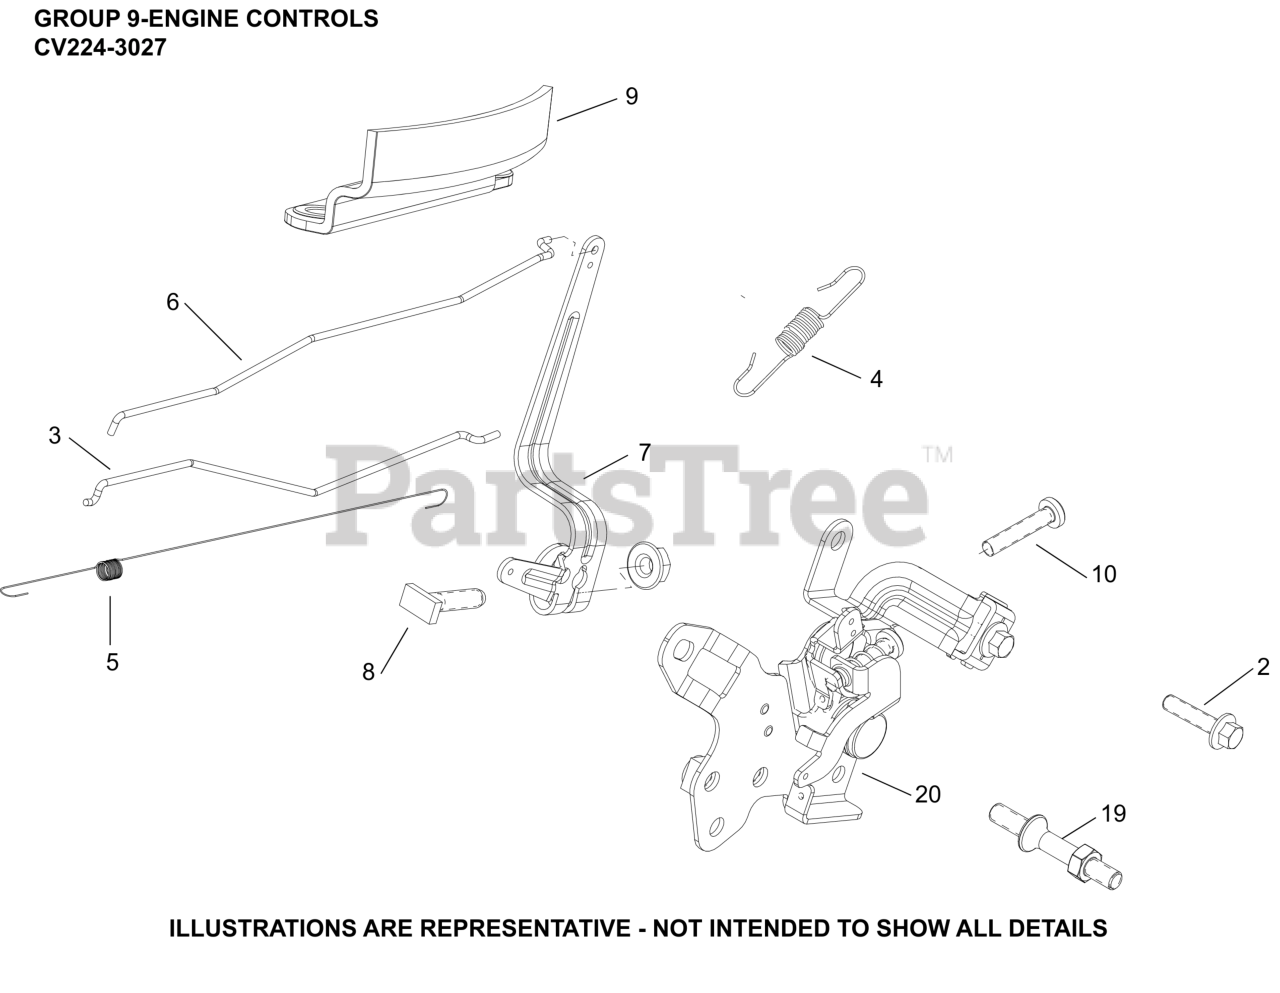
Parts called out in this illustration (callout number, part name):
2	SCREW, (M5) HEX FLANGE
3	LINKAGE, CHOKE
4	SPRING, GOV (2800-3300 RPM)
5	SPRING, LINKAGE
6	LINKAGE, GOVERNOR
7	LEVER, GOVERNOR
8	SCREW, RECTANGLE HEAD (M6)
9	GUARD, FINGER
10	SCREW, SPEED ADJUSTING
NI	CONTROL ASSY, REMOTE VARIABLE SPEED
